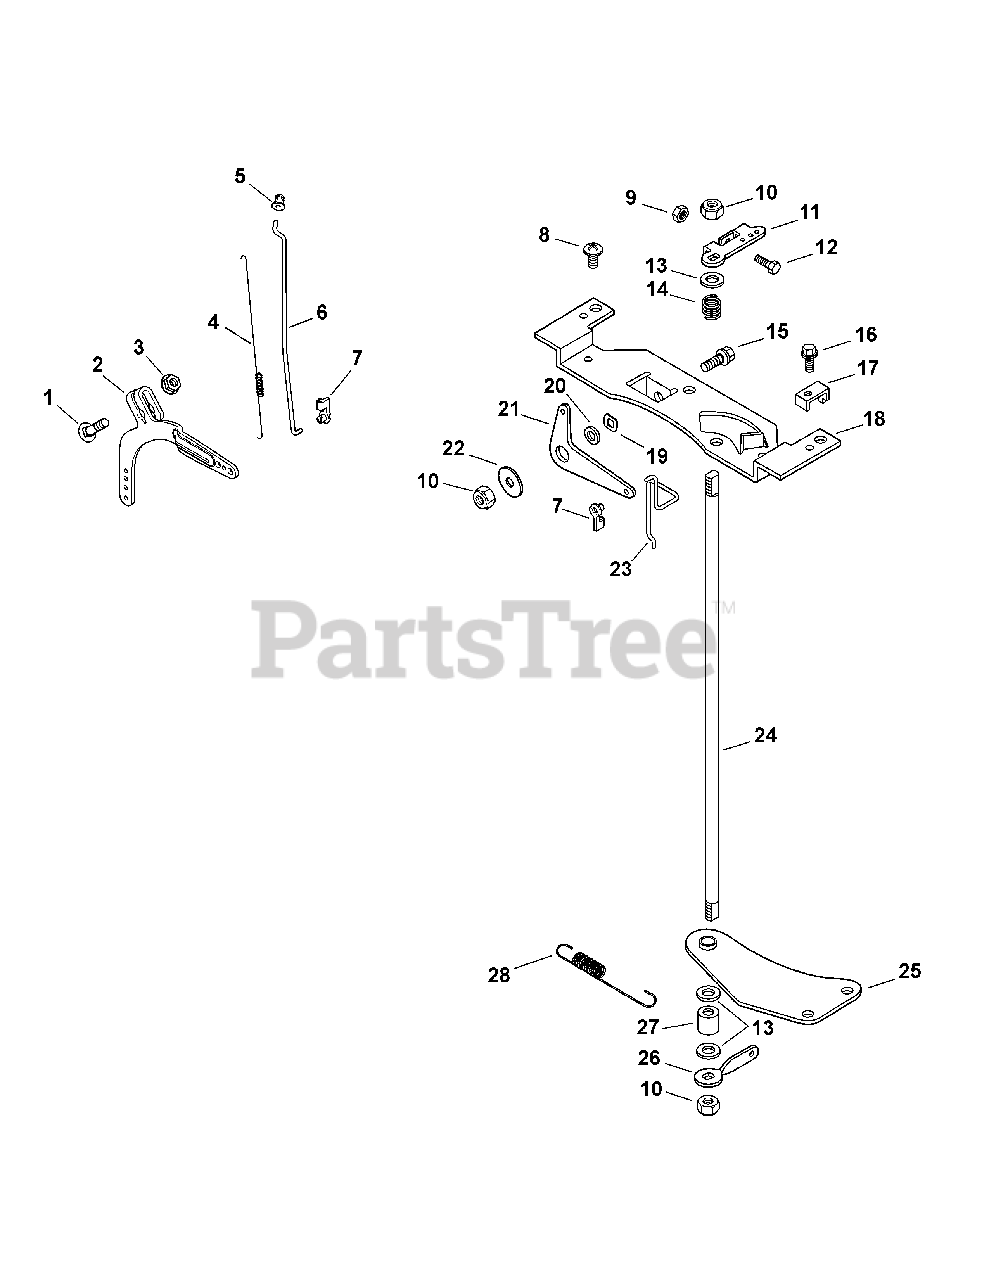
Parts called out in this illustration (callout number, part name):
1	Bolt, M6 x 1.0 x 25
2	Governor Lever
3	Flange Nut, M6 x 1.0
4	Linkage Spring
5	Linkage Retaining Bushing
6	Throttle Linkage
7	Throttle Linkage Bushing
8	Screw, 11-16 x 3/4
9	Nut, M4 x 0.7
10	Lock Nut, M6 x 1.0
11	Throttle Control Lever
12	Cap Screw, M4 x 0.7 x 30
13	Flat Washer, 1/4
14	Throttle Shaft Spring
15	Flange Screw, M6 x 1.0 x 16
16	Flange Screw, M5 x 0.8 x 16
17	Cable Clamp
18	Control Bracket
19	Spring Washer, 3/8
21	Choke Lever
22	Flat Washer, 1/4
23	Choke Linkage
24	Throttle Shaft
25	Throttle Shaft Bracket
26	Throttle Control Lever
28	Governor Spring
